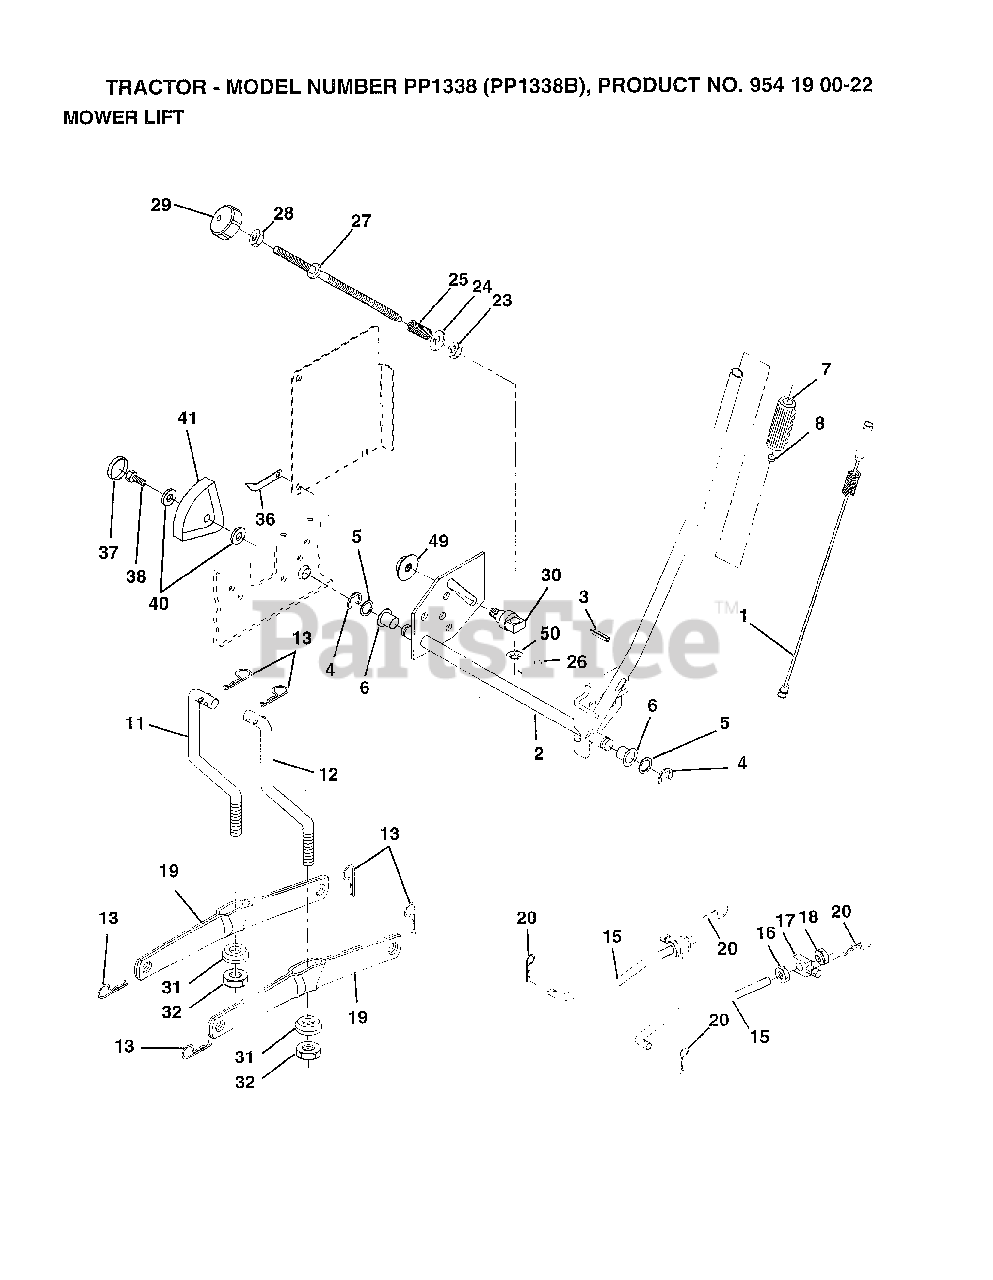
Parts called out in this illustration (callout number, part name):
1	WIRE ASM W.SPRING
2	"SHAFT ASM LIFT,RH"
3	PIN-GROOVE LT
5	WASHER
6	NYLON BEARING
7	GRIP
15	LINK.FRONT
16	NUT
17	TRUNION
18	NUT.LK.W/WSH.1/2.
19	ARM SUSP REAR
20	RETAINER SPRING
23	NUT T
24	WASHER
25	SPRING T
28	NUT
29	KNOB INF 3/8-16
30	TRUNNION
31	BEARING PVT LH
32	NUT.CROWNLOCK.3/8
36	POINTER-INDICAT
37	"PLUG,HOLE"
38	SCREW
40	WASHER
41	HEIGHT INDICATOR
49	NUT.HXFLG.LOCK.
